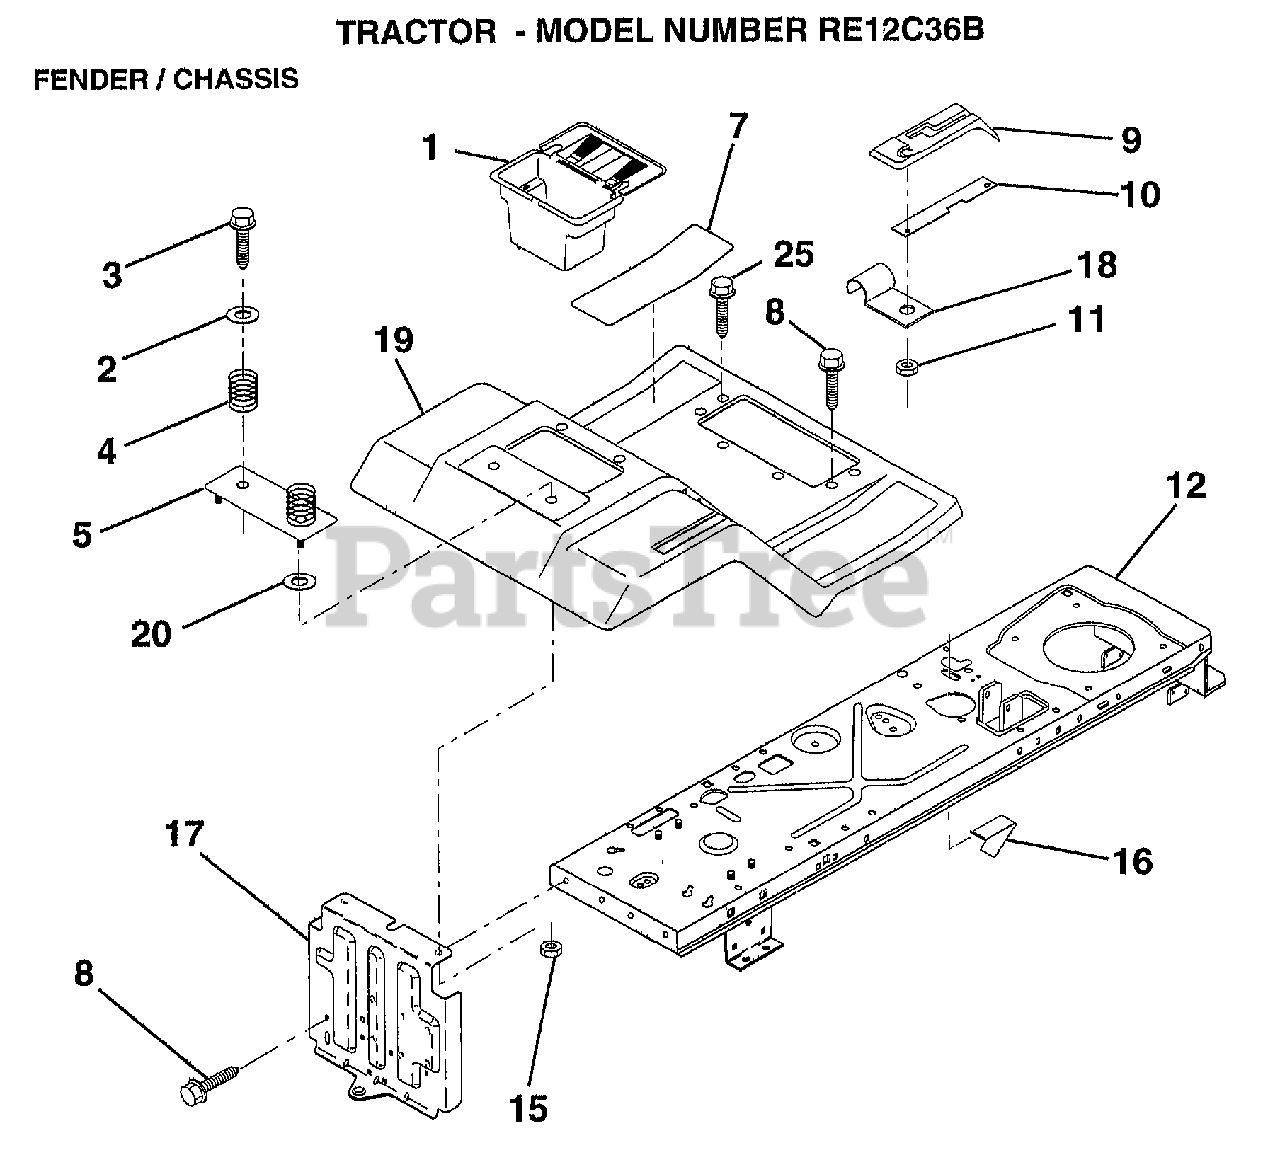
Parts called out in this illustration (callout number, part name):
1	"CASE,BATTERY.MECH"
2	WASHER
3	SCREW
4	SPRING COMPRESSIO
5	BTRY FENDER PLATE
7	PAD FOOTREST
8	SCREW
9	CONSOLE.SHIFT CONTROL
10	PLATE LOCK SHIFT
11	NUT
12	CHASSIS, ASSY, WELDMENT
15	NUT HXKEP 1/4X20
17	DRAWBAR ASM LR
18	"CLIP,INSULATOR"
19	FENDER/FOOT MS505
25	SCREW
